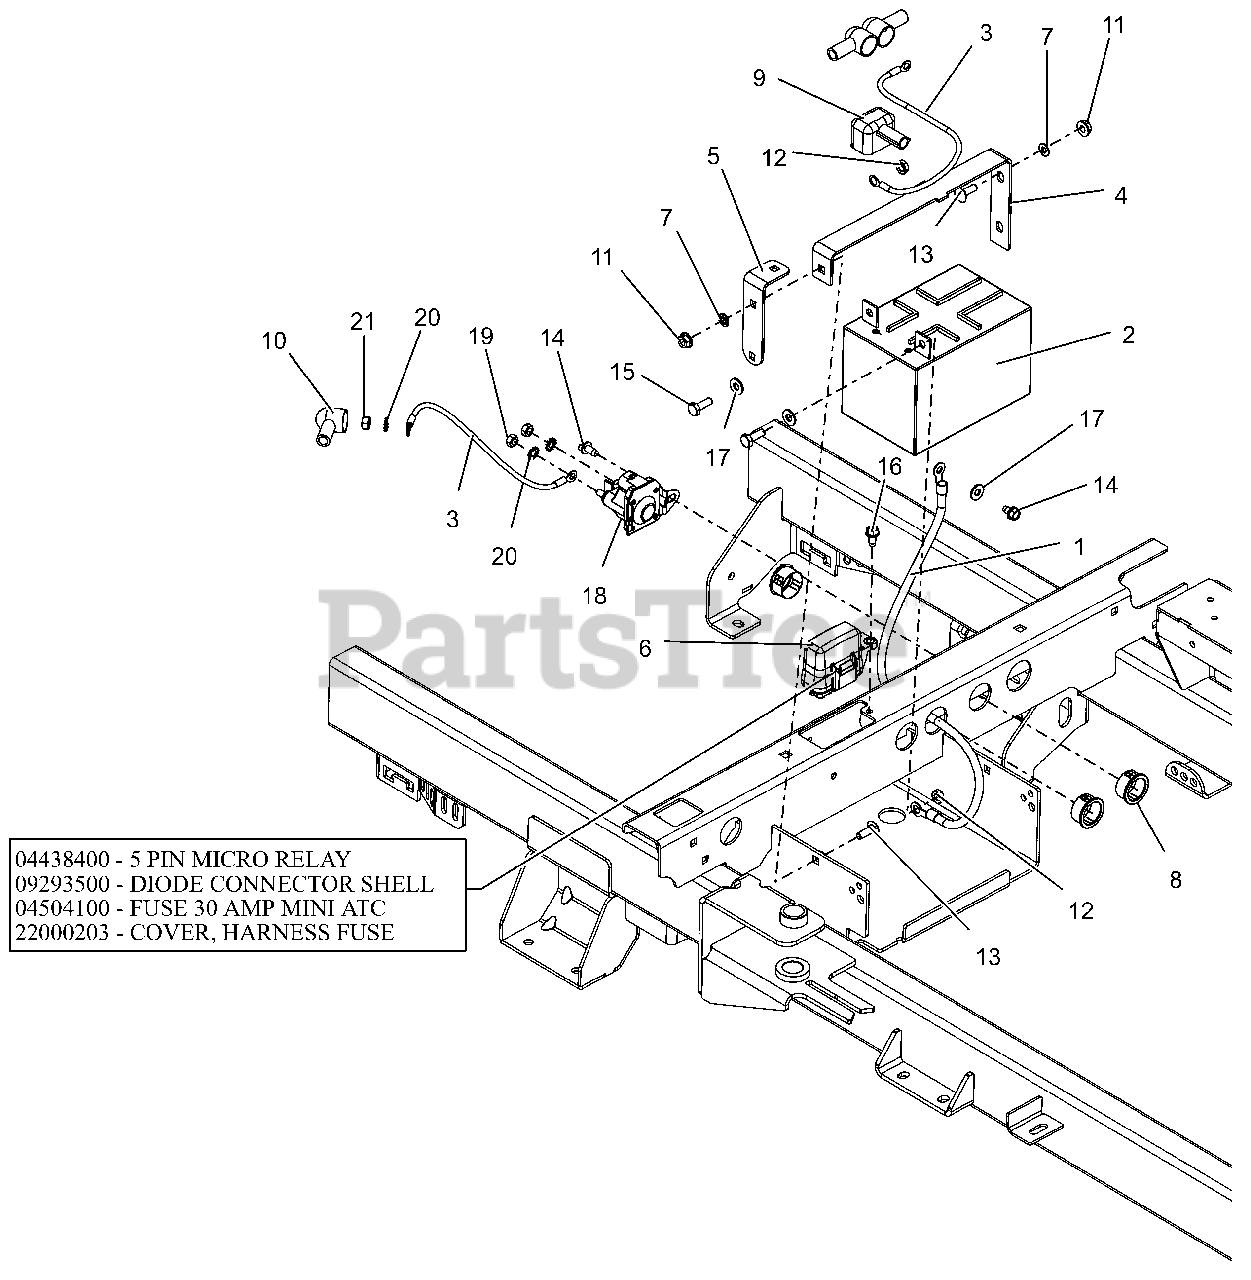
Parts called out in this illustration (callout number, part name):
1	CABLE-NEGATIVE BATTERY 24.00"
2	BATTERY, 12V 12A-190CCA
3	CABLE,POS W/2 1/4 RING 15.0 LG
4	BRKT, BATTERY HOLD-DOWN
5	BRKT, BATTERY HOLD DOWN
6	HARNESS, WIRE-4POS KEY IKON/ZT
6	RELAY,MICRO5 TERML W/RESISTOR
6	DIODE, CONNECTOR SHELL
6	FUSE,30 AMP MINI-ATC
6	COVER, FUSE
7	NUT-PUSH .25X.50 O.D.
8	BSHG, PANEL SNAP .937X1.11X.56
9	INSULATOR
10	BOOT, EYELET TERMINAL
11	NUT-LK-TOP-FLG .250-20 GF ZCC
12	NUT-KEPS .250-20
13	BLT, RHSN .25-20X.750 G5 ZCC
14	SCR-TAP .25-20X.
15	BLT, HEX .25-20X.75 G5 ZCC
16	SCR-TAP .25-20X.50 HWH ZCC
17	WSHR,FLT .281X.625X.065 ZCC
18	SOLENOID, STARTER (SEALED)
19	NUT-STD M6-1.0 ZCC
20	WSHR,LK-EXT.262X.502X.026 ZCC
21	NUT-STD .250-20 G2 ZCC
